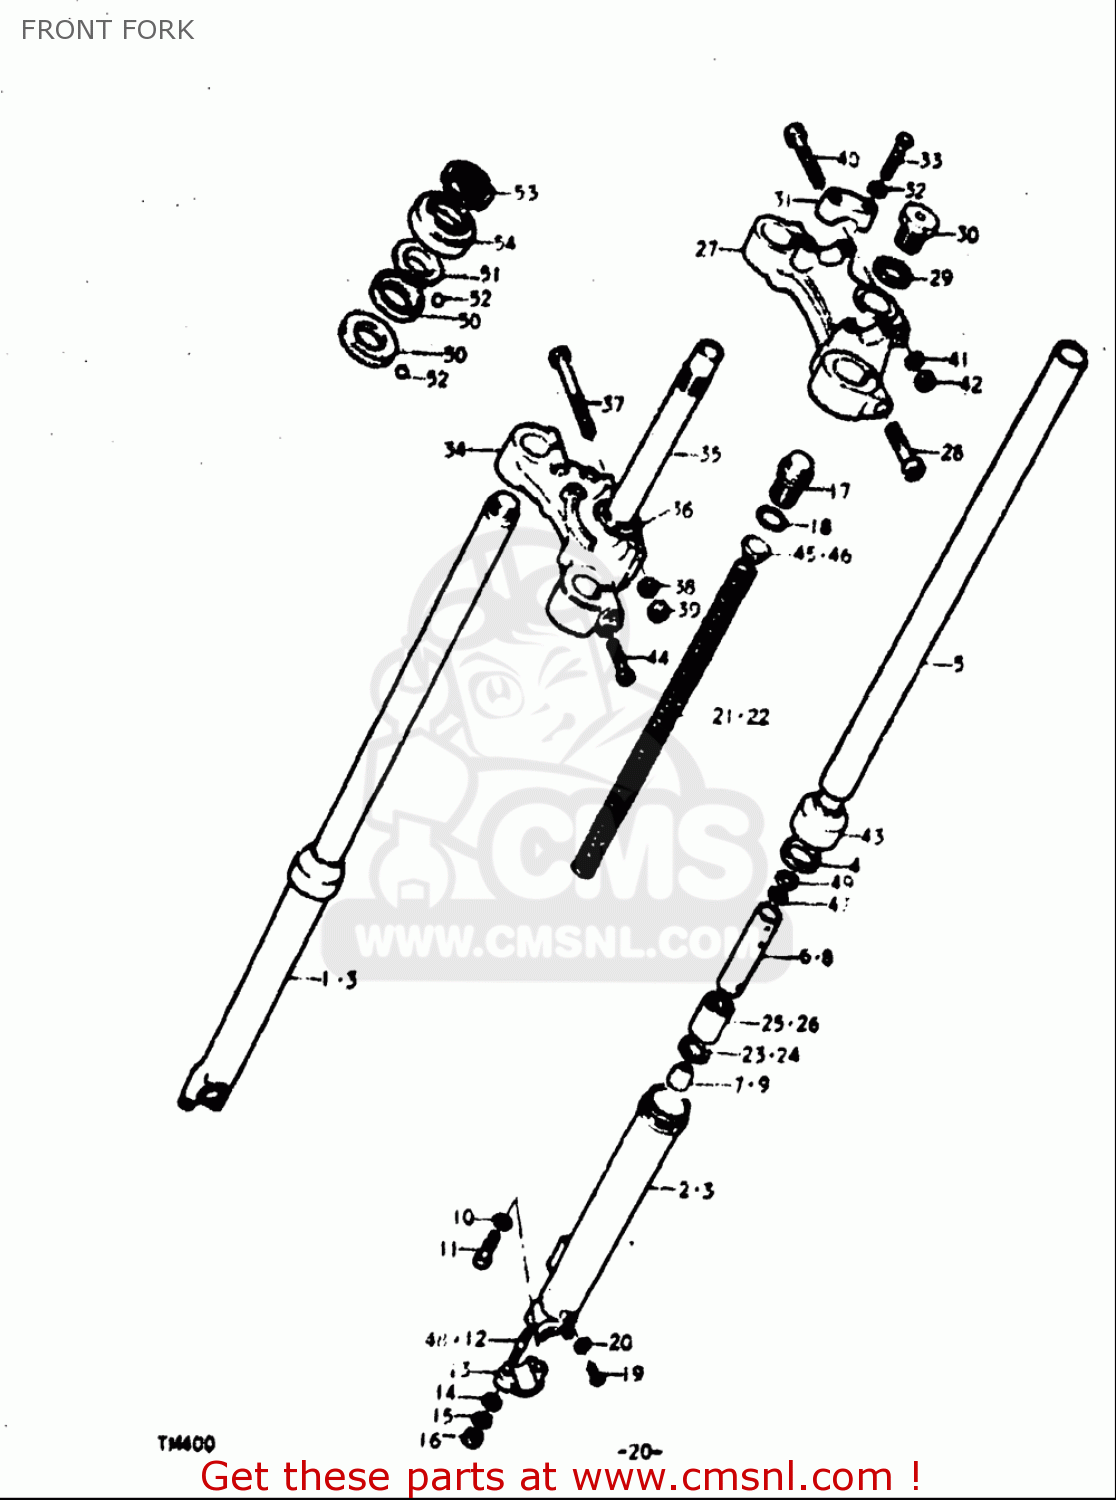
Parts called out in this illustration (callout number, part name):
4	SEAL,OIL
11	BOLT,FORK CYLINDER(10X25)
12	STUD BOLT
14	WASHER
15	WASHER,LOCK
16	NUT
18	O-RING,FORK FITTING BOLT
19	SCREW
20	GASKET,DRAIN,PLUG (NAS)
30	CAP
32	WASHER,LOCK
33	BOLT
36	RACE,STEERING OUTER LWR
37	BOLT
38	WASHER,LOCK
39	NUT
40	BOLT
41	WASHER,LOCK
42	NUT
44	BOLT
48	BOLT,STUD
49	WASHER
50	LACE,STEERING INNER LWR
51	LACE,STEERING OUTER UPR
52	BALL
53	NUT,STEERING STEM(25X44X10)
54	DUST SEAL,STEERING UPR
